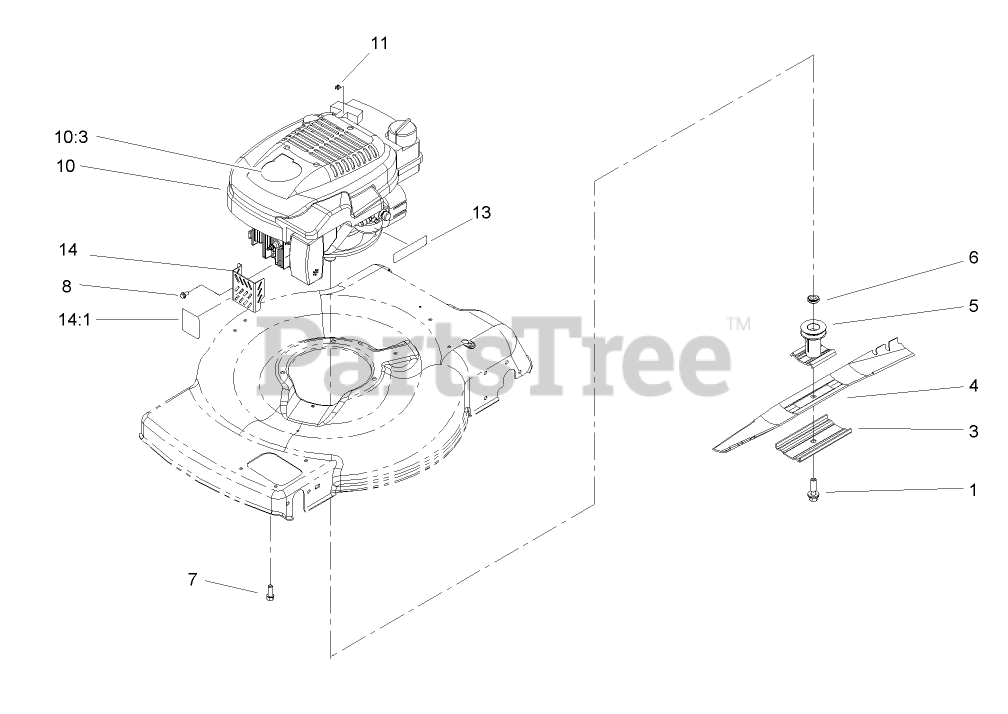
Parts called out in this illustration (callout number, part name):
5	DRIVER-BLADE
6	SPACER-DRIVER
7	SCREW-TAPTITE
8	SCREW-HWH
10	Loose Parts Package
10:3	DECAL-RECOIL
11	STOP-ROPE
13	DECAL-PRIMER
14	MUFFLER GUARD ASM
14:1	DECAL-WARNING
